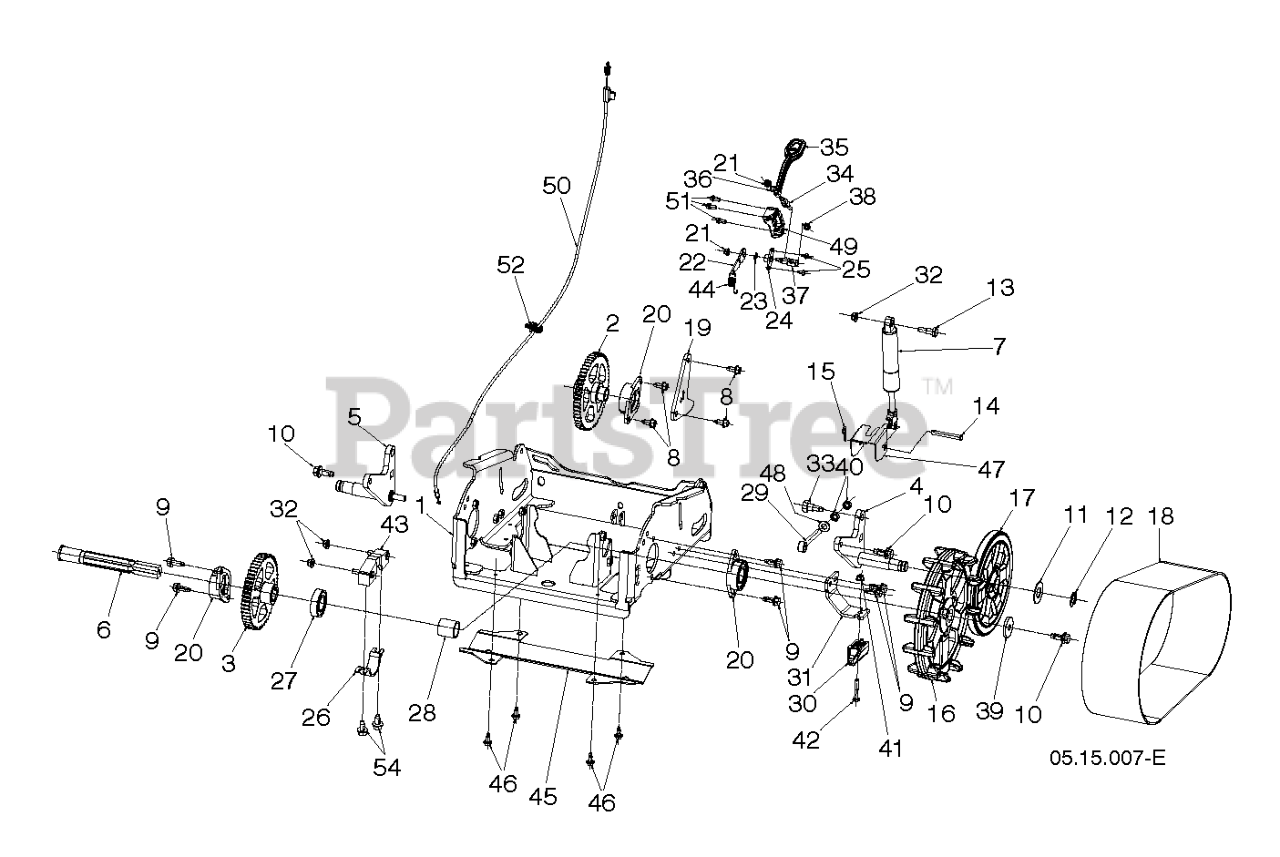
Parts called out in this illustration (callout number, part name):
2	GEAR TRACK TRANSMISSION
3	GEAR TRACK
4	ARM TRACK ADJUSTER WELDMENT LH
5	ARM TRACK ADJUSTER WELDMENT RH
6	AXLE TRACK HEX
7	Actuators
8	BOLT.HEX.HD.WASHER.5/16-18X.75
9	SCREW HEXAGON HEAD FLANGE 5/16
10	SCREW HEXAGON HEAD FLANGE 3/8-
11	WASHER.HARDENED
13	BOLT SHOULDER 10MM
15	RETAINER M
20	CARRIER BEARING
21	NUT HEX; NYLON LOCKING; FLANGE
23	WASHER WAVE 3/8
24	BUSHING BUCKET HEIGHT ADJUSTER
26	MOUNT BEARING
27	BEARING SEALED R16-2RS
28	SPACER TRACK AXLE
29	ROD END SOLID, 3/8
32	NUT HEXAGON FLANGE 5/16-18 ST
34	ROD LEVER CONTROL
36	DISC SPRING
37	AXLE BUCKET HEIGHT CONTROL
38	NUT HEXAGON 1/4-20 ST ZPB
39	SPACER PLATE .38 X 1.5
40	NUT NUT.3/8-16.HEX.JAM.Z 3/8-1
41	NUT FLG, NYLOCK, 1/4-20 GR G C
42	Bolt Hex Fin 1/4-20 Unc x 1-1/2
43	MOUNT BEARING
44	SPRING EXTENSION - DRIVE
46	HEX.WASHER.HEAD 1/4-20 X .65
48	WASHER PLAIN WASHER 3/8 X 0.08
49	BRACKET BUCKET HEIGHT LEVER BU
50	CABLE ASSY BUCKET HEIGHT ADJUS
51	SCREW.HWH.13-16X.50
52	CABLE, 1/4 BLACK FIR TREE
